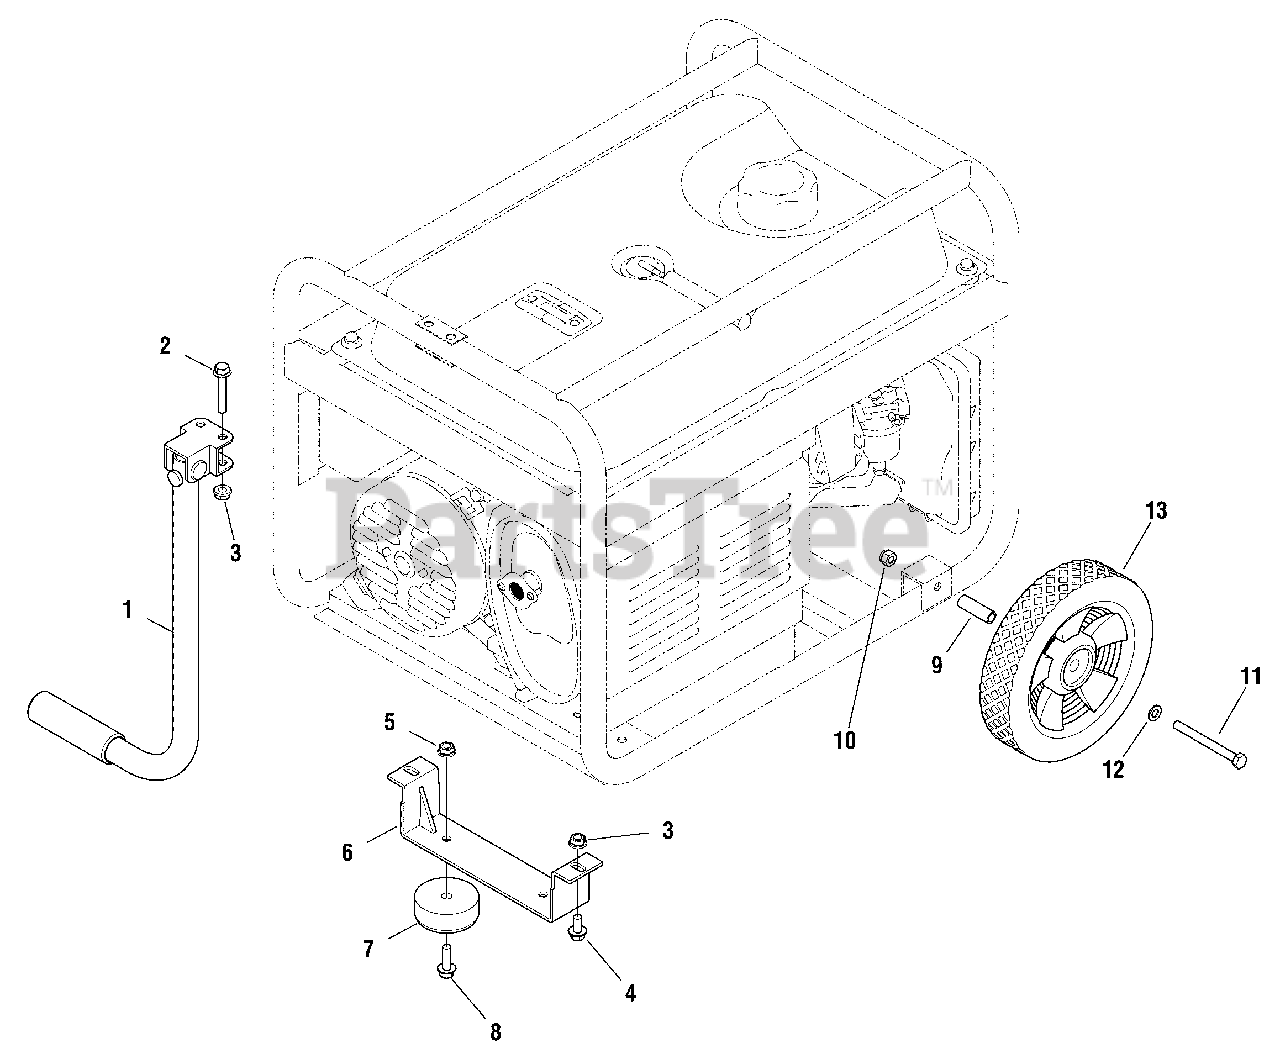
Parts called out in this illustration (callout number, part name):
2	* BOLT, M8 x 45
3	* NUT, Flange, M8
4	* BOLT, M8 x 16
5	* NUT, Flange, M6
8	* BOLT, M6 x 25
10	* NUT, Locking, M8
12	* WASHER, Flat, M8
